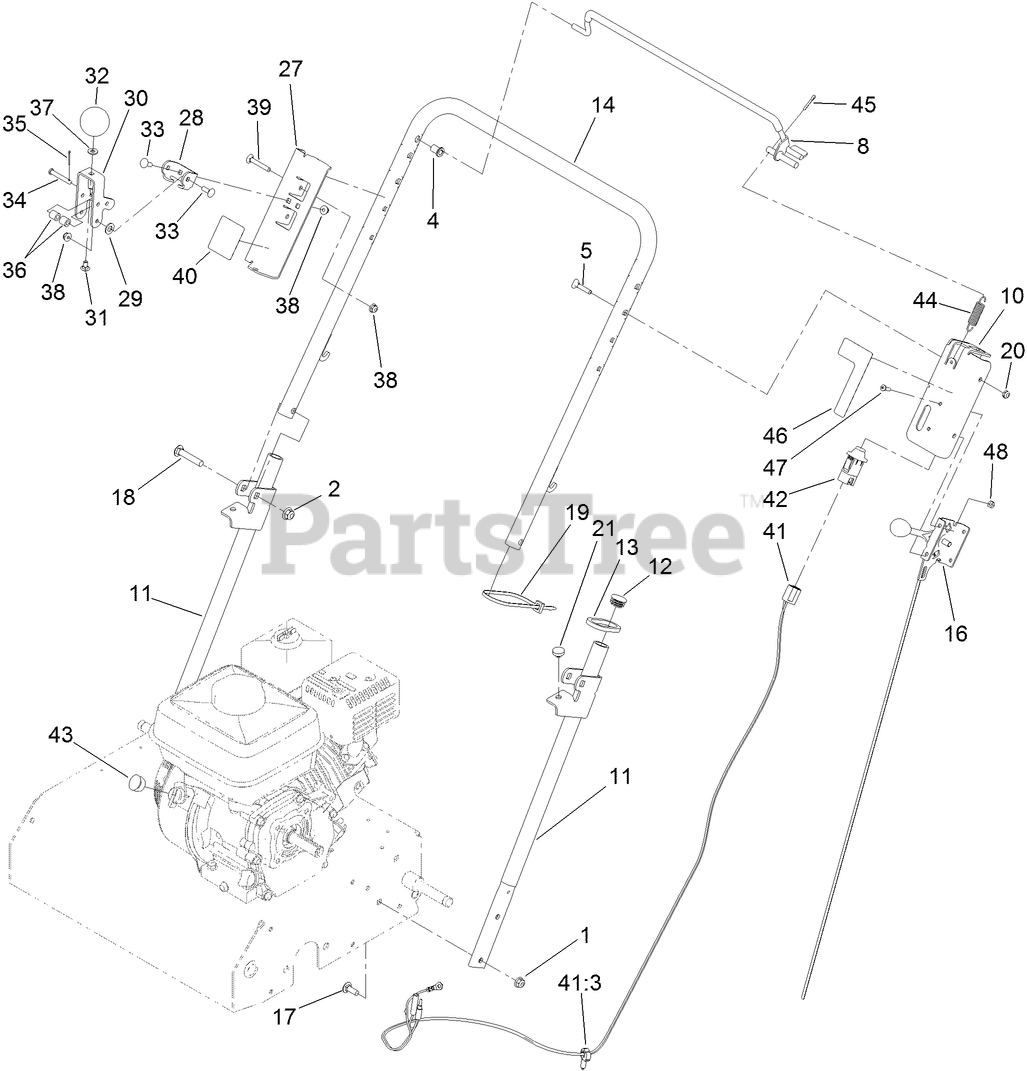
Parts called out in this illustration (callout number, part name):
1	NUT-HF, NI
2	NUT-HF, NI
4	BUSHING
5	BOLT-HANDLE
10	BRACKET-THROTTLE
13	RING-HANDLE LOCK
14	HANDLE-UPPER
16	CABLE-THROTTLE
17	BOLT-CARR
18	SCREW-CARR
19	TIE-CABLE
20	NUT-LOCK, NI
21	BUMPER
27	BRACKET-ADJUST, FLOW
28	BRACKET-ADJUST, FLOW
29	WASHER-FLAT
30	LEVER-ADJUST, FLOW
31	SCREW-CARR
32	KNOB-RATE, FLOW
33	BOLT-CARR
34	PIN-CLEVIS
35	PIN-COTTER
36	SPACER
37	WASHER-FLAT
38	NUT-HF
39	SCREW-CARR
40	DECAL-SEED GATE
41	HARNESS-WIRE
41:3	CLIP-HARNESS
42	SWITCH-PLUNGER
43	PLUG-ENGINE
44	SPRING-EXTENSION
45	PIN-COTTER
46	DECAL-THROTTLE
47	SCREW-PPH
48	NUT-LOCK, NI
